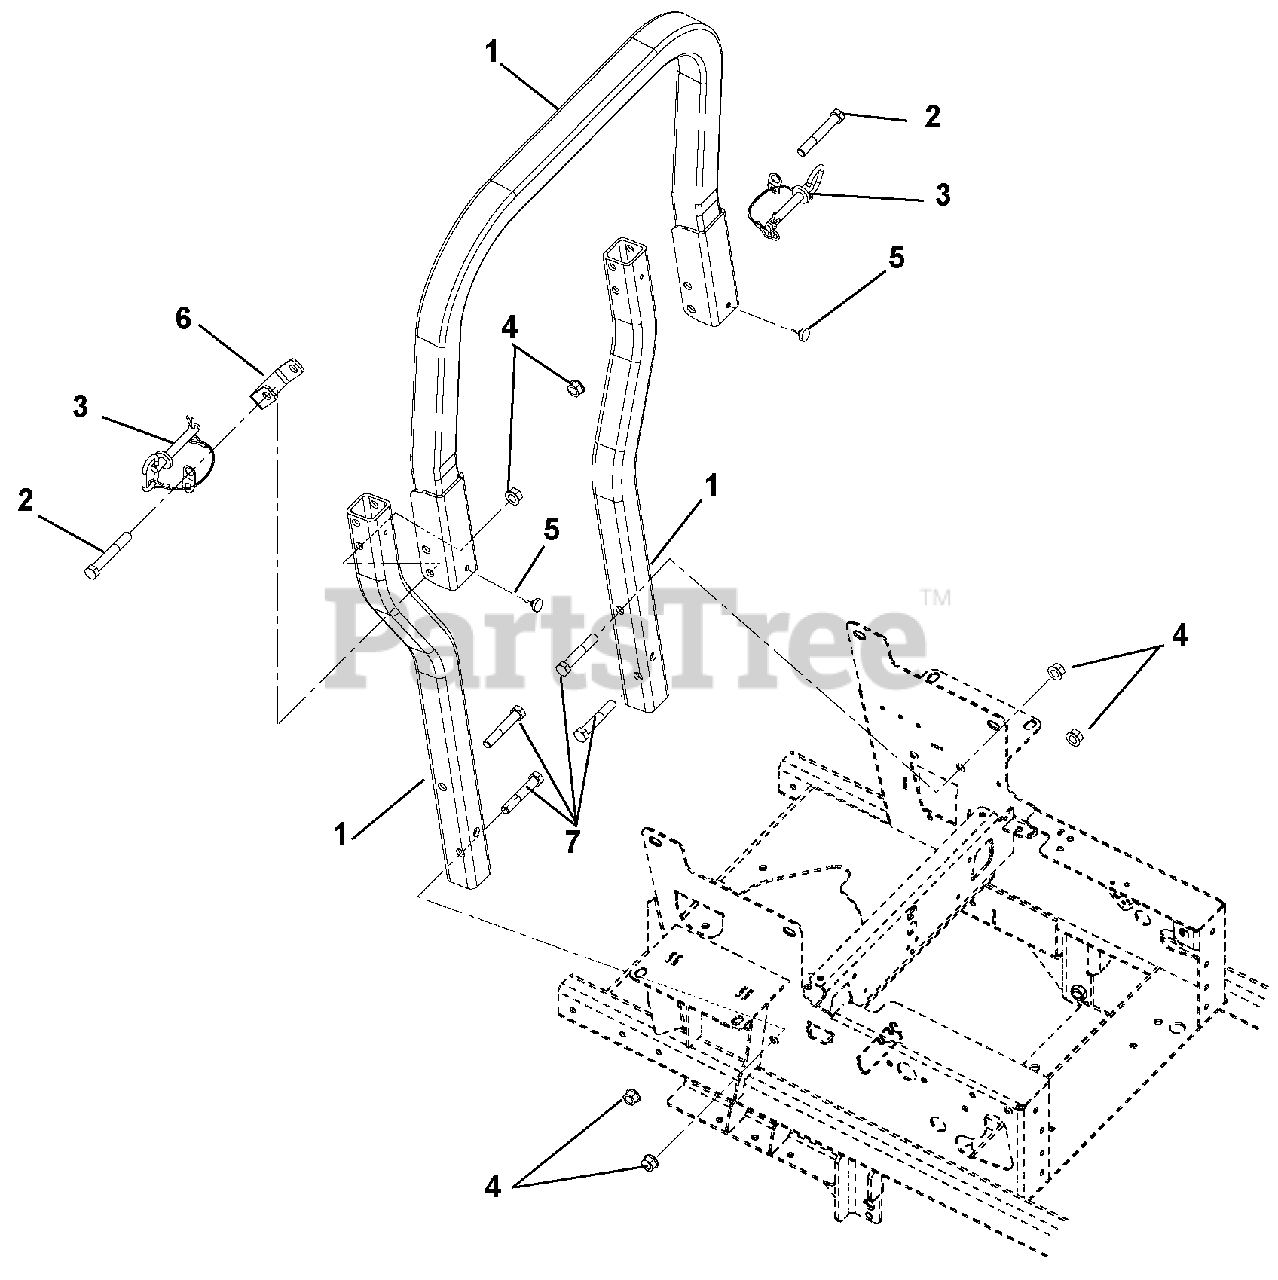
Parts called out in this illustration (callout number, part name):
1	ROPS, PT100 Replacement
2	Bolt, Hex .50-13 x 3.50
3	Assembly, ROPS Pin/Lanyard
4	Nut, Locking-Top-Flange .50-13
5	Bumper, ROPS Rubber
6	Bracket, ROPS Stop, Pro-Turn
7	Bolt, Hex .50-13 x 3.00
